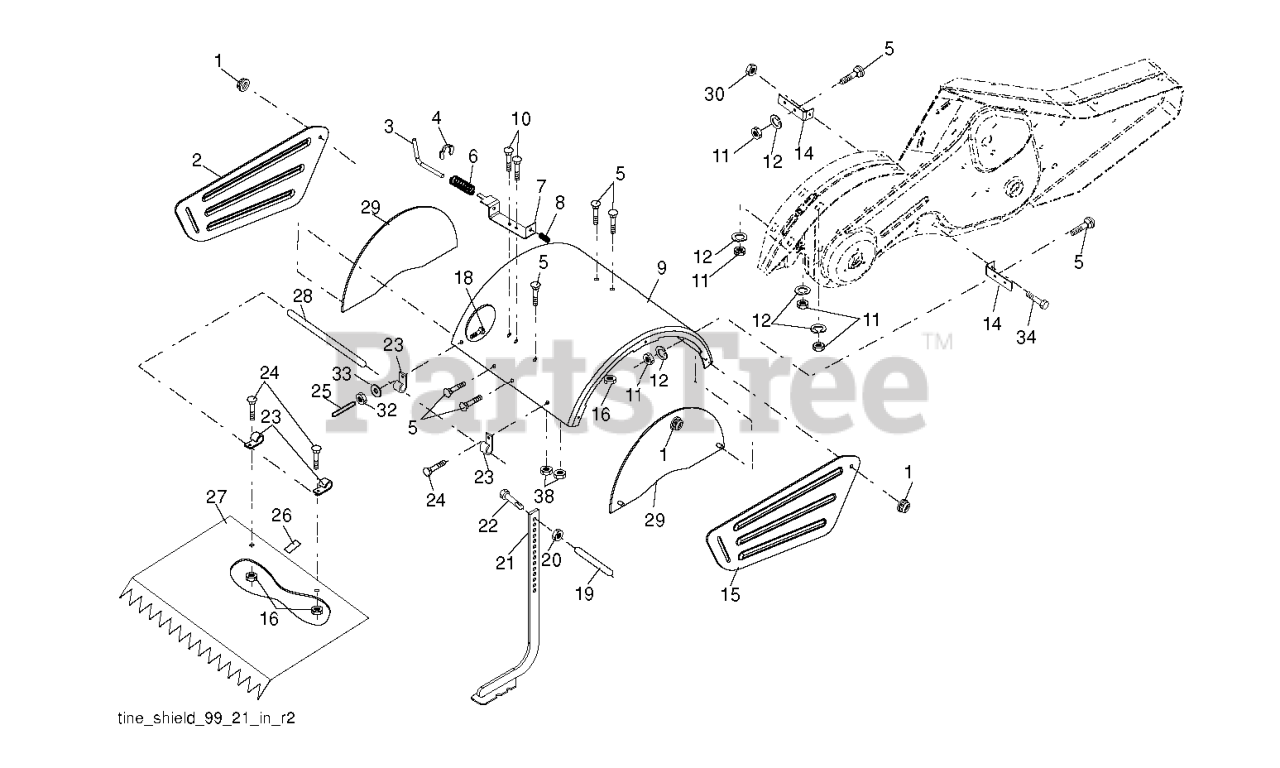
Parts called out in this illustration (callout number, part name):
1	NUT LOCK HEX FLANGE 5/16-18
2	SHIELD.SIDE.OUTER.LH.ORANGE
3	STAKE PIN TI
4	RING, KLIP
5	BOLT, RDHD SQNK 5/16-18 X 3/4
7	BRACKET.LATCH.STAKE.3.20.BLACK
8	SPRING CRT
9	SHIELD.TINE.TILLER.ORANGE
12	WASHER.LOCK.HVY.HLCL.SPR.5/16
14	BRACKET.TINE.SHIELD.TILLER
15	SHIELD.SIDE.OUTER.RH.ORANGE
16	NUT T
20	NUT.HEX.3/8-16UNC
21	STAKE.ASM.DEPTH
22	BOLT.375-16
25	VINYL CAP TI
26	PAD IDLER TI
27	SHIELD.PNT.LEVELING.ORANGE.668
28	PIN, HINGE
29	SHIELD.ASM.PNT.SIDE.ORANGE.668
30	LOCKNUT-FLANGE 5/16-18
32	NUT
33	LOCKWASHER
34	Bolt Hex Flanged 5/16-18 Unc x 2
38	NUT
